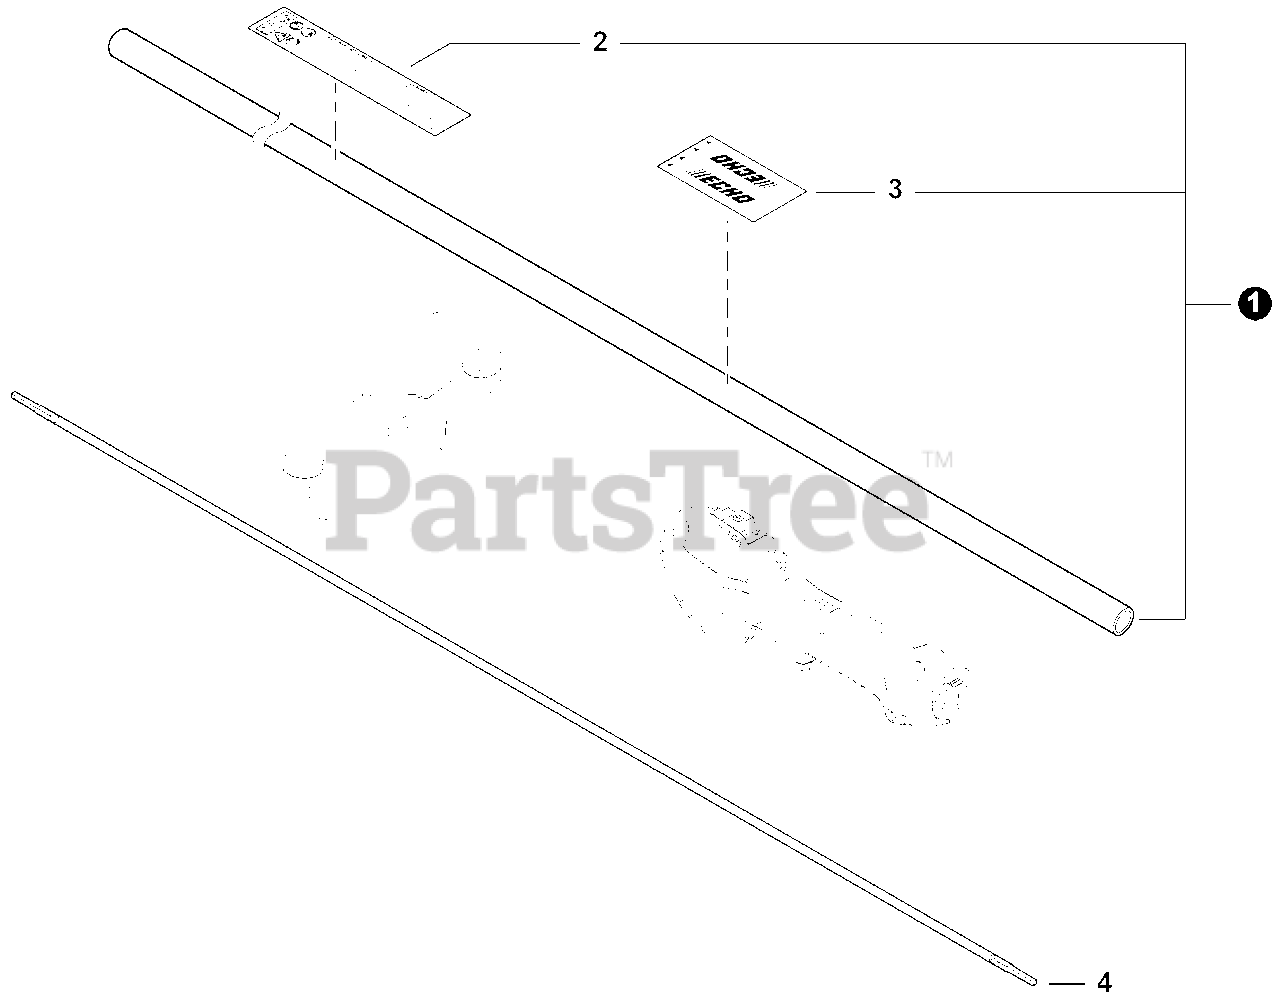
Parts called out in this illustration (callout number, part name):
1	MAIN PIPE ASSY
2	LABEL, CAUTION
3	LABEL, HANDLE LOCATION
4	DRIVESHAFT - FLEXIBLE
